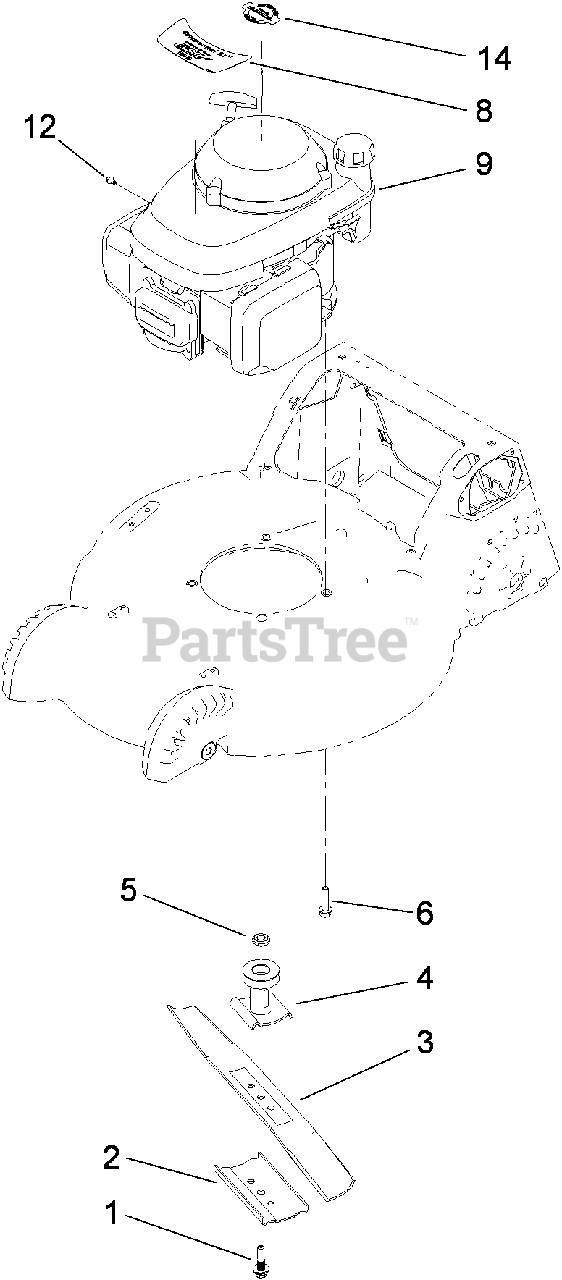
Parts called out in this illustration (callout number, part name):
1	BOLT-SHOULDER
2	SUPPORT-BLADE
3	BLADE-BAGGING
4	DRIVER-BLADE
5	Spacer-Driver
6	SCREW-HWH
8	DECAL-ENGINE
12	SCREW-HWH
14	DECAL-ENGINE
